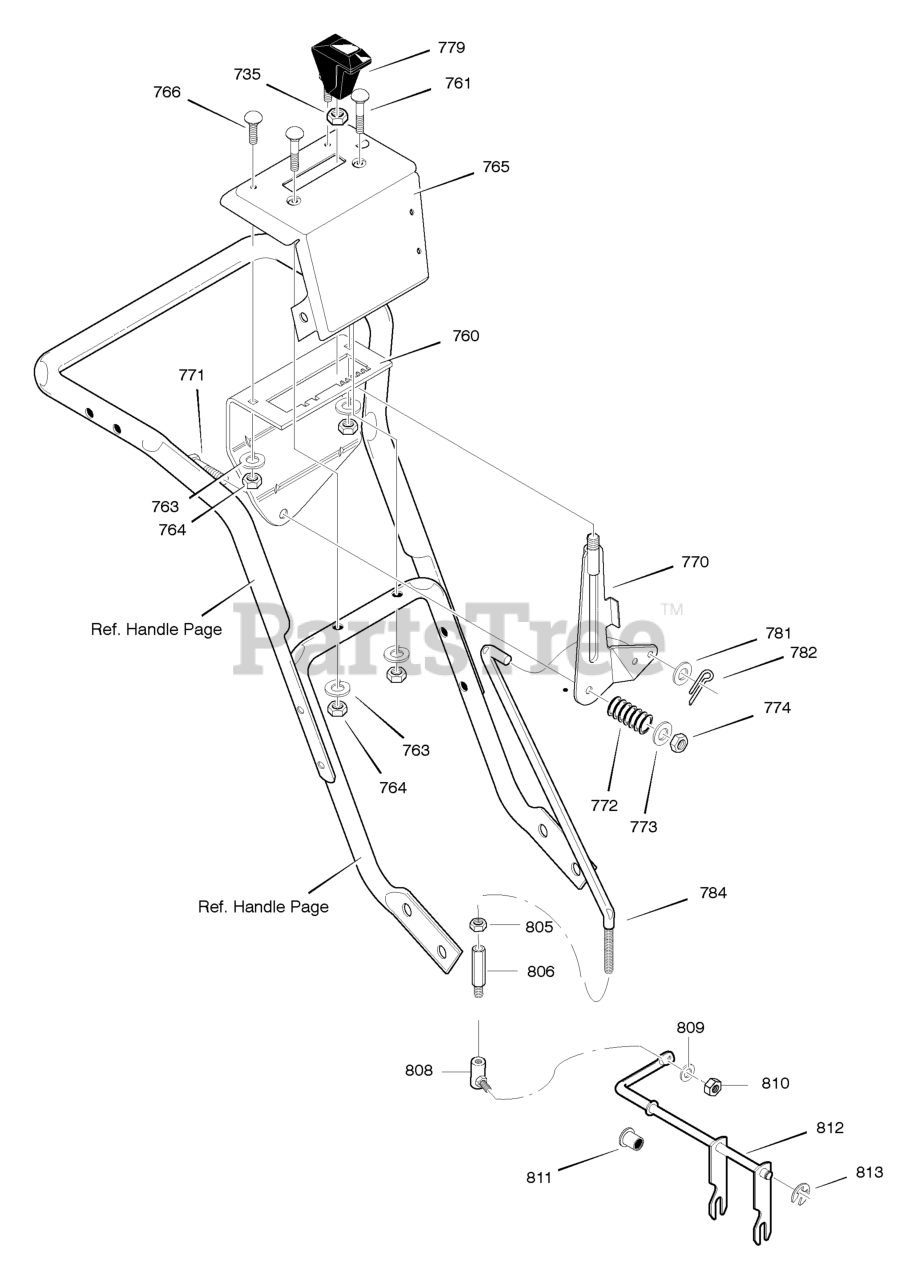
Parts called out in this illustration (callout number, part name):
735	NUT, 3/8-16 HEXJAM
760	BRACKET, SHIFT CONTROL
761	CARR. BOLT, 1/4-20 X 2
763	WASHER, SPLIT
764	NUT, 1/4-20 HEX
765	CONTROL PANEL
766	CARR. BOLT, 1/4-20 X 0.63
770	SHIFT LEVER ASSY
771	SCREW, 5/16-18 x 1.75
773	FLATWASHER
774	NUT, 5/16-18 NYLON HEX
781	WASHER, FLAT .349X.69X.066
782	PIN, COTTER
784	ROD, SPEED CONTROL
805	NUT, 5/16-18
806	ADAPTER, SPEED ROD -YZ
808	BALLJOINT, STEEL -YZ
809	WASHER
810	NUT, 5/16-24
811	FLANGED BEARING
812	ROD ASSY, YOKE PANEL
813	RING, RETAINER
